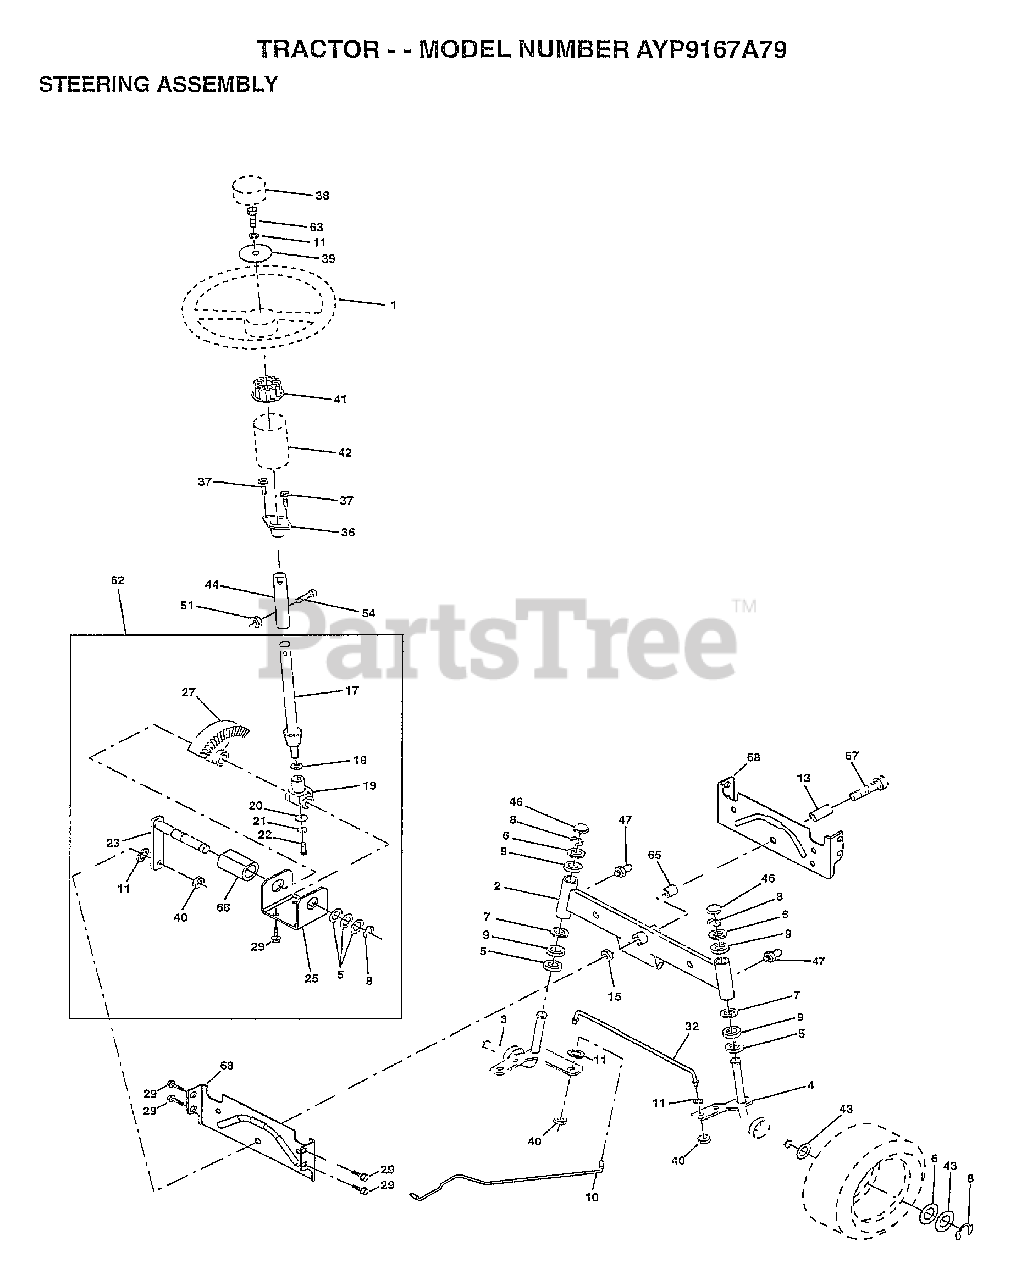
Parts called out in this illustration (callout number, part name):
1	WHEEL STR AYP BLK
3	SPINDLE ASM LH
4	SPINDLE AMS RH
5	WASHER .T
6	WASHER
7	WASHER
8	RING
9	COL. SRTG. BEAR.
10	LINK.DRAG
11	LOCKWASHER
13	BEARING AXLE
15	"NUT-LOC,FLANGE LT"
17	SHAFT ASM STEERIN
18	THRUST WASHER
19	SUPPORT.SHAFT
21	LOCKWASHER
22	SCREW.SCKTHD.CAP
25	BRKT-STEERING
27	GEAR SECTOR
29	SCREW
32	ROD.ASM.TIE.BALL
36	BUSHING.STEERING
37	"SCREW-TT,10-32 FL"
38	CAP STEER AYP
39	WASHER T
40	GRIPCO NUT
41	ADAPTER LT
42	BOOT.STEER.PL
43	WASHER
44	EXT SHAFT STEERIN
46	CAP
47	ZERK M
51	NUT
54	BOLT
62	KIT STEERING ASM
63	BOLT
65	SPACER AXLE
66	"BEARING-ARM,PITMA"
67	BOLT
68	BRACE AXLE
